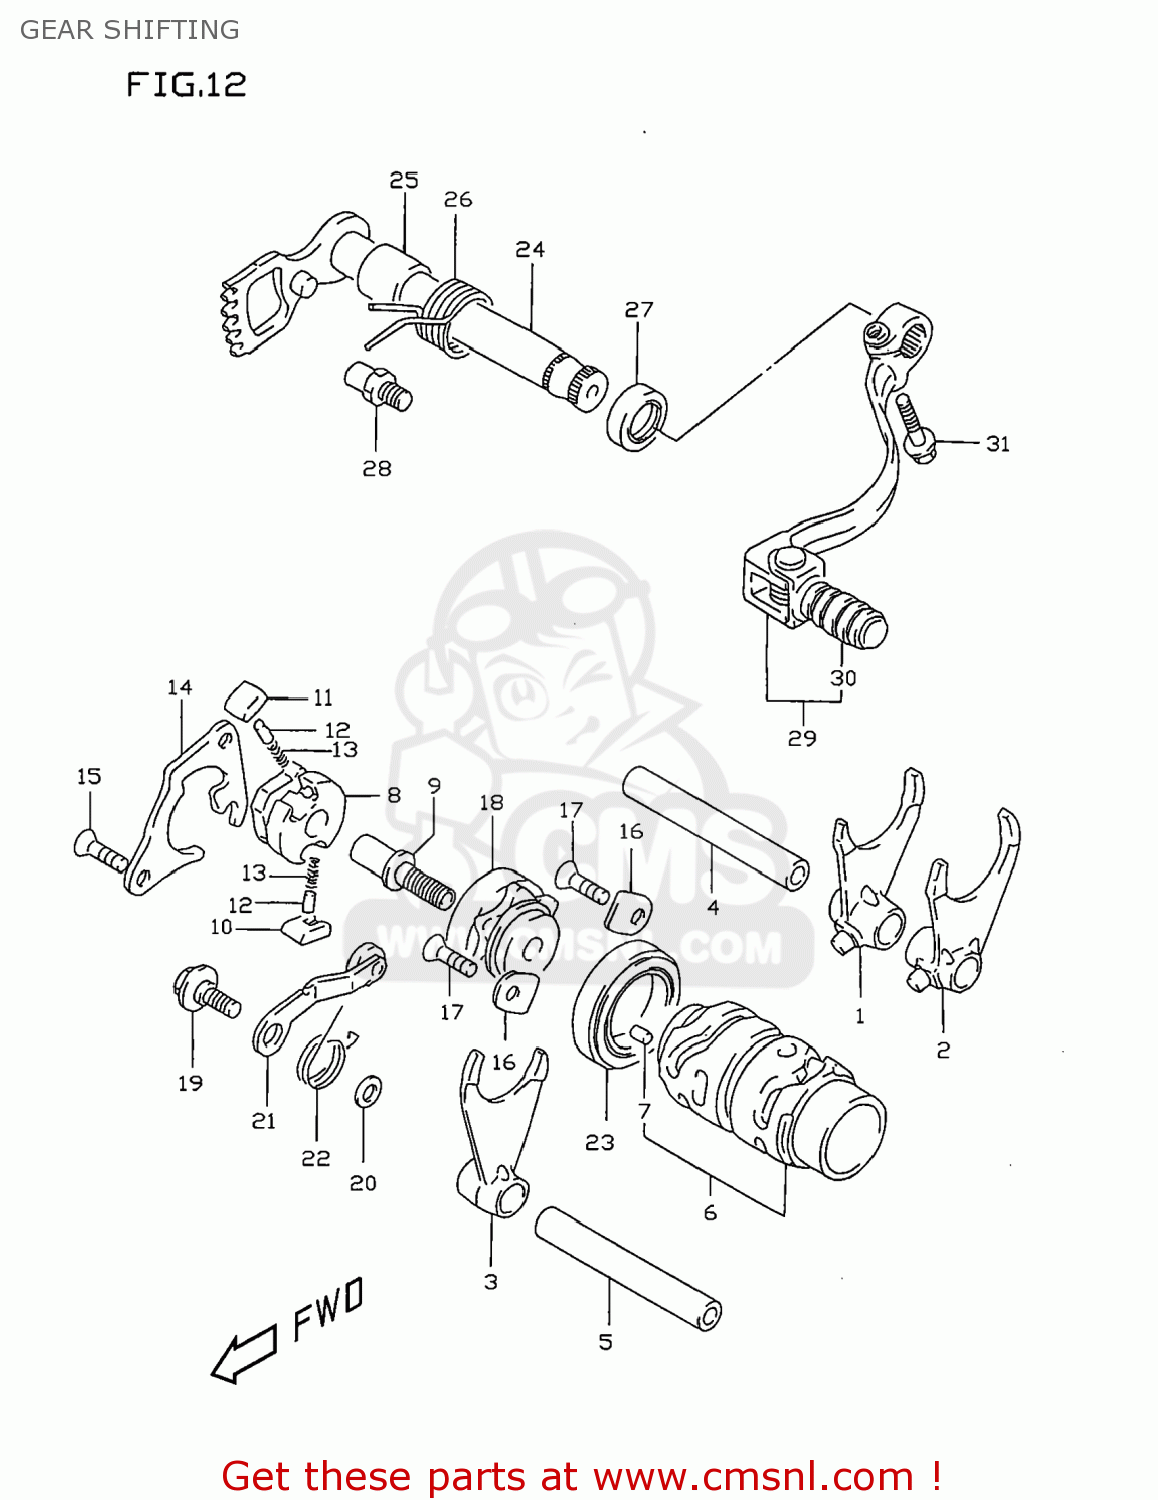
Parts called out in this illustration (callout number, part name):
1	FORK,GEAR SHIFT NO.1
2	FORK,GEAR SHIFT NO.2
3	FORK,GEAR SHIFT NO.3
4	SHAFT,GEAR SHIFT FORK
5	SHAFT,GEAR SHIFT FORK
6	CAM,GEAR SHIFT
7	PIN
8	GEAR,GEARSHIFT CAM DRIVE
9	PIN,SHIFT CAM DRIVEN GEAR
10	PAWL,GEAR SHIFT NO.1
11	PAWL,GEAR SHIFT NO.2
12	PIN(5X8)
13	SPRING
14	LIFTER,GEAR SHIFT POLE
15	SCREW
16	RETAINER,COUNTER BEARING,R
17	SCREW
18	PLATE,SHIFT CAM STOPPER
19	BOLT(6X14.3)
20	WASHER
21	STOPPER,SHIFT CAM
22	SPRING
23	BEARING
24	SHAFT,GEAR SHIFT
25	SPACER(14X20X17.5)
26	SPRING
27	SEAL,OIL(14X22X6)
28	STOPPER,GEAR SHIFT CAM
29	LEVER ASSEMBLY,GEAR SHIFTING
30	RUBBER,GEAR SHIFT PEDAL
31	BOLT,G/S SWITC
